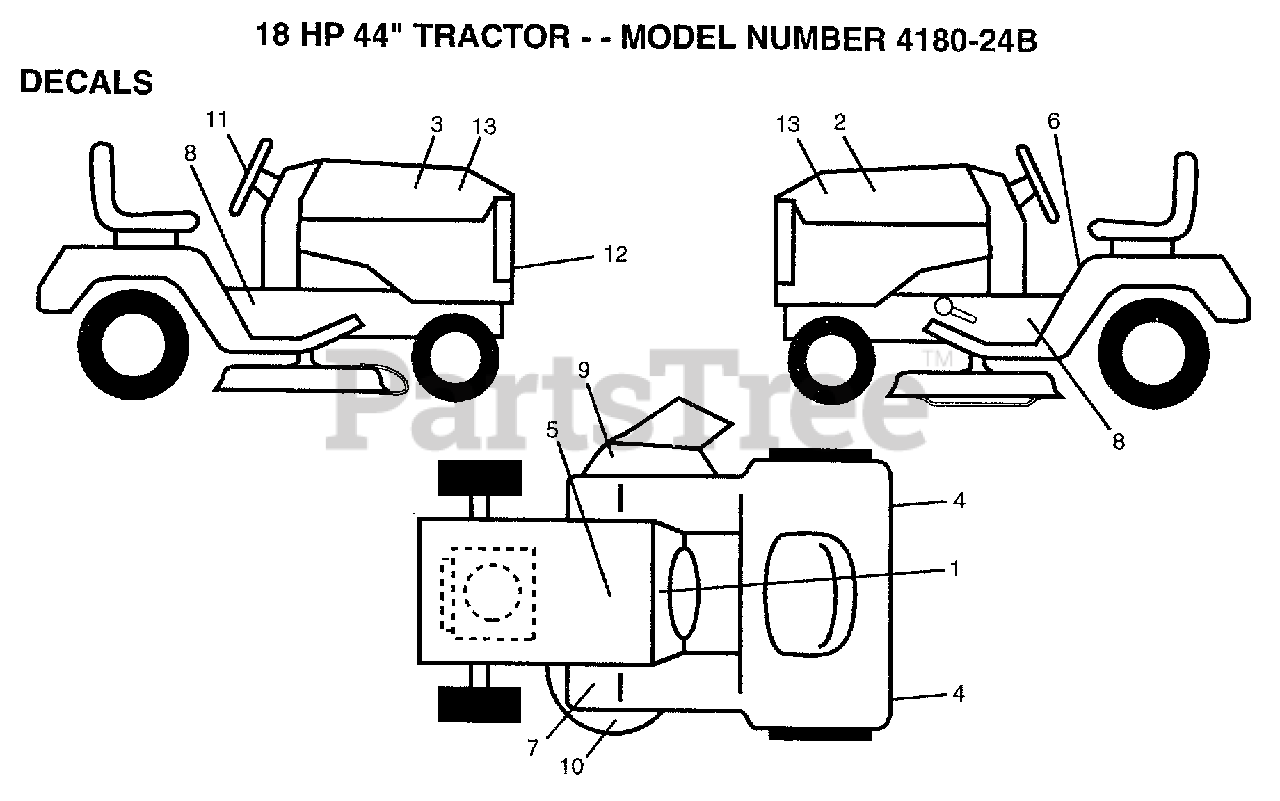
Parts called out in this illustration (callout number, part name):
2	HOOD DECAL LH
4	REFLECTOR-TAIL YT
5	DECAL
6	DECAL
9	DECAL WARING
10	DECAL INSTRUCTION CAUTION
12	GRILL DECAL
13	NAMEPLATE LOGO
